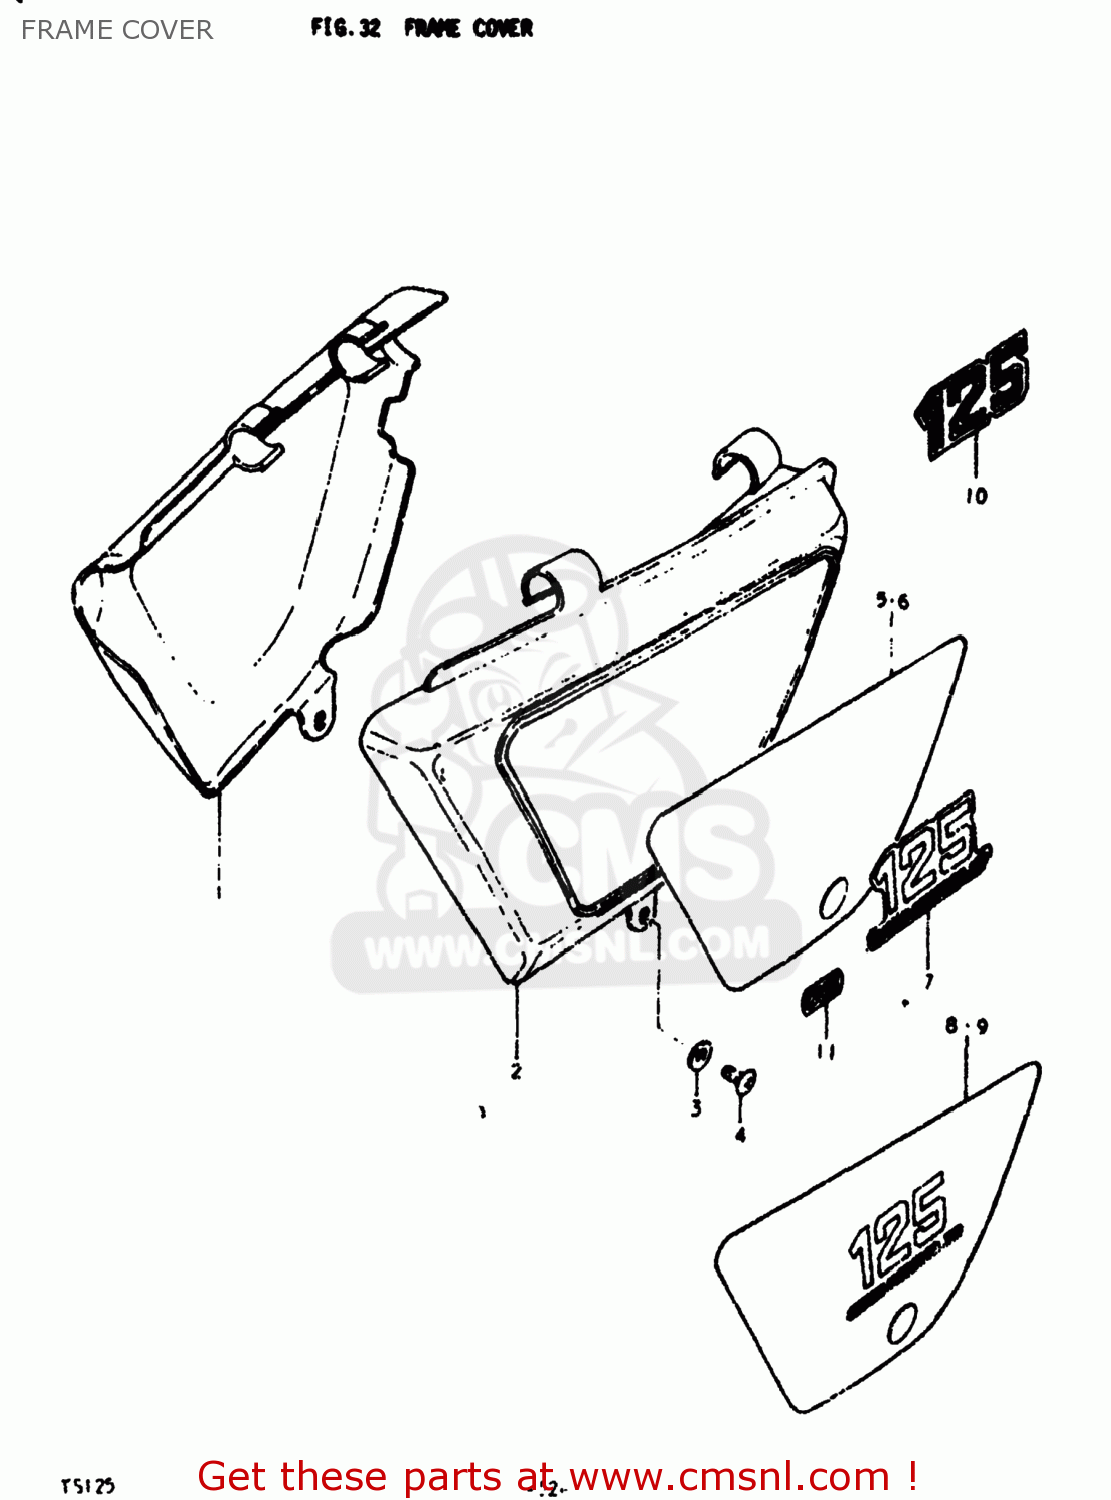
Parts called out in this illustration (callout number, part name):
1	COVER,FRAME,RIGHT
2	COVER,FRAME,LEFT
3	WASHER
4	SCREW 6X12
5	EMBLEM
6	EMBLEM,FRAME COVER
7	EMBLEM
8	EMBLEM
9	EMBLEM,FRAME COVER
10	EMBLEM
11	EMBLEM,CCIS
